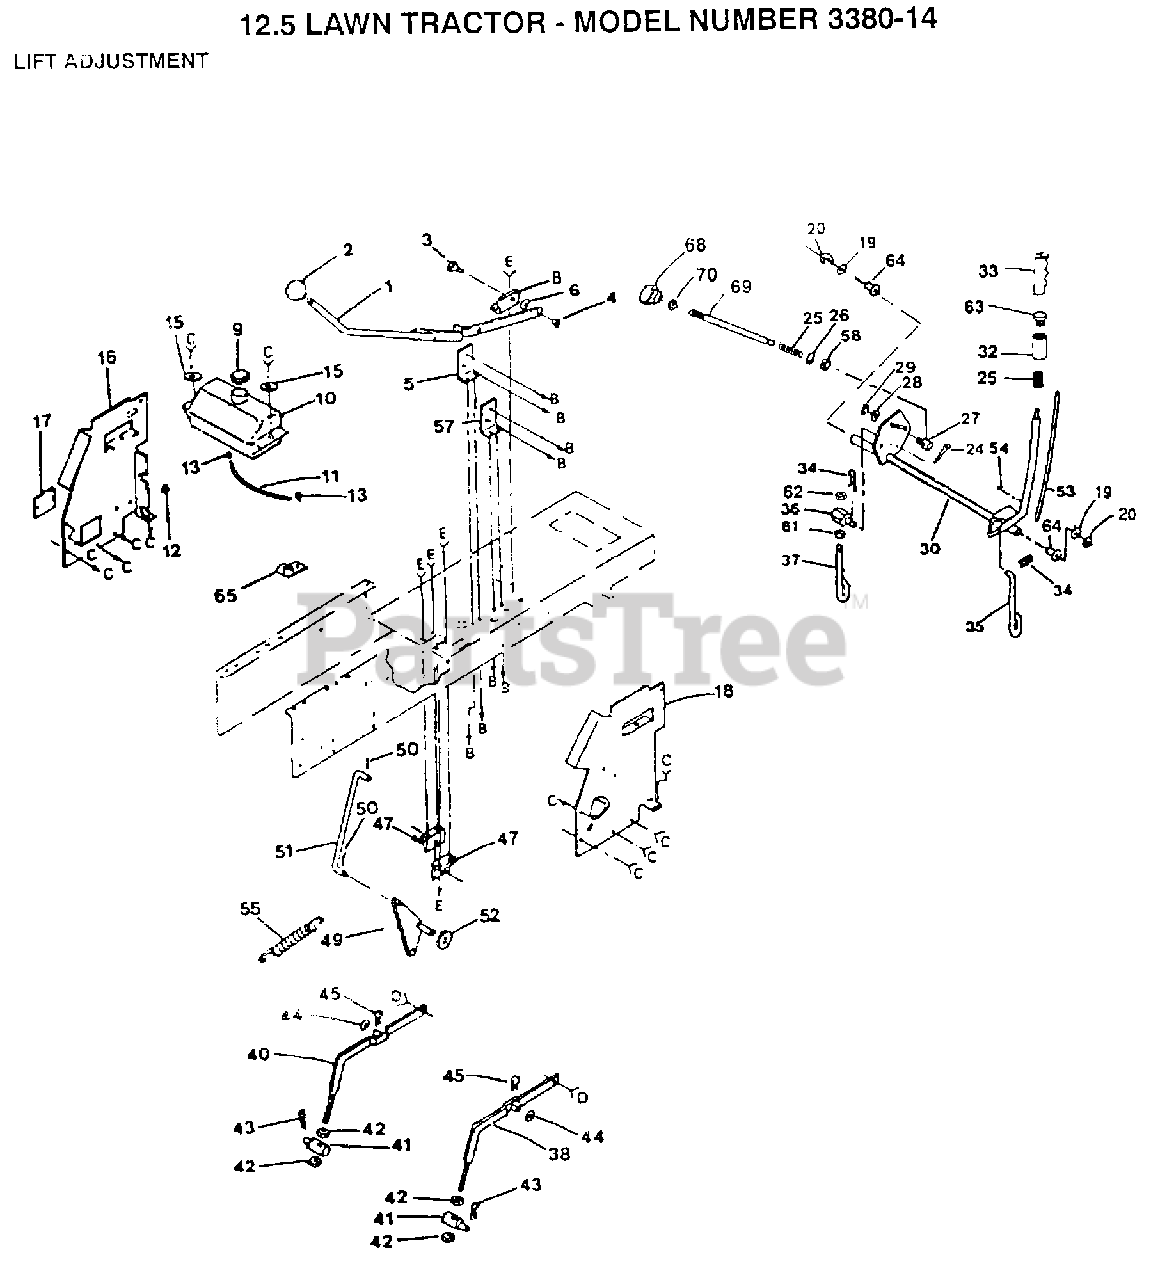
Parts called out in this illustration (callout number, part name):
3	"BOLT, SHOULDER LT"
5	"BRACKET,SWITCH LT"
8	"SUP,LVR,CLUTCH LT"
10	TANK.FUEL.LT.
13	HOSE CLAMP
15	WASHER
16	PANEL DASH LH
17	COVER ACCESS
19	WASHER
24	TRUNION LT
26	WASHER
28	WASHER
29	KLIP RING
33	GRIP
35	LIFT LINK LT
37	PIVOT PIN T
38	RH SUSP ARM ASM
40	LH SUSP ARM ASM
42	NUT
43	SPRING H
45	SPRING.RETAINER
47	"BRKT,BELLCRAN T"
49	"T, BELLCRANK"
50	COTTER PIN
52	WASHER
54	PIN-GROOVE LT
57	BRACKET LT
58	NUT T
61	NUT
64	NYLON BEARING
65	INSUL CLIP T
68	HDLE ADJ LIFT
70	NUT
